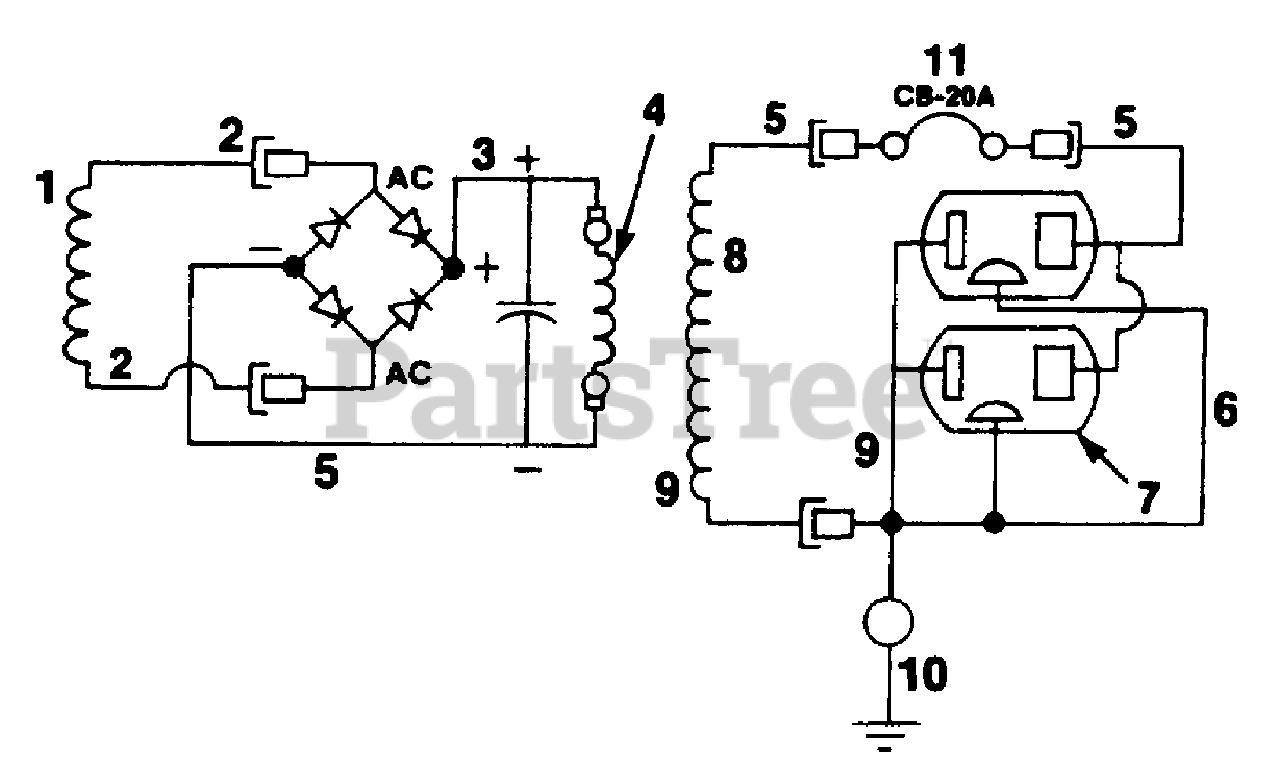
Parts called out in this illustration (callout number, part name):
1	QUAD COIL
2	YELLOW
3	RED
4	FIELD COIL
5	BLACK
6	GREEN
8	MAIN COIL
9	WHITE
10	GROUND
11	CIRCUIT BREAKER
